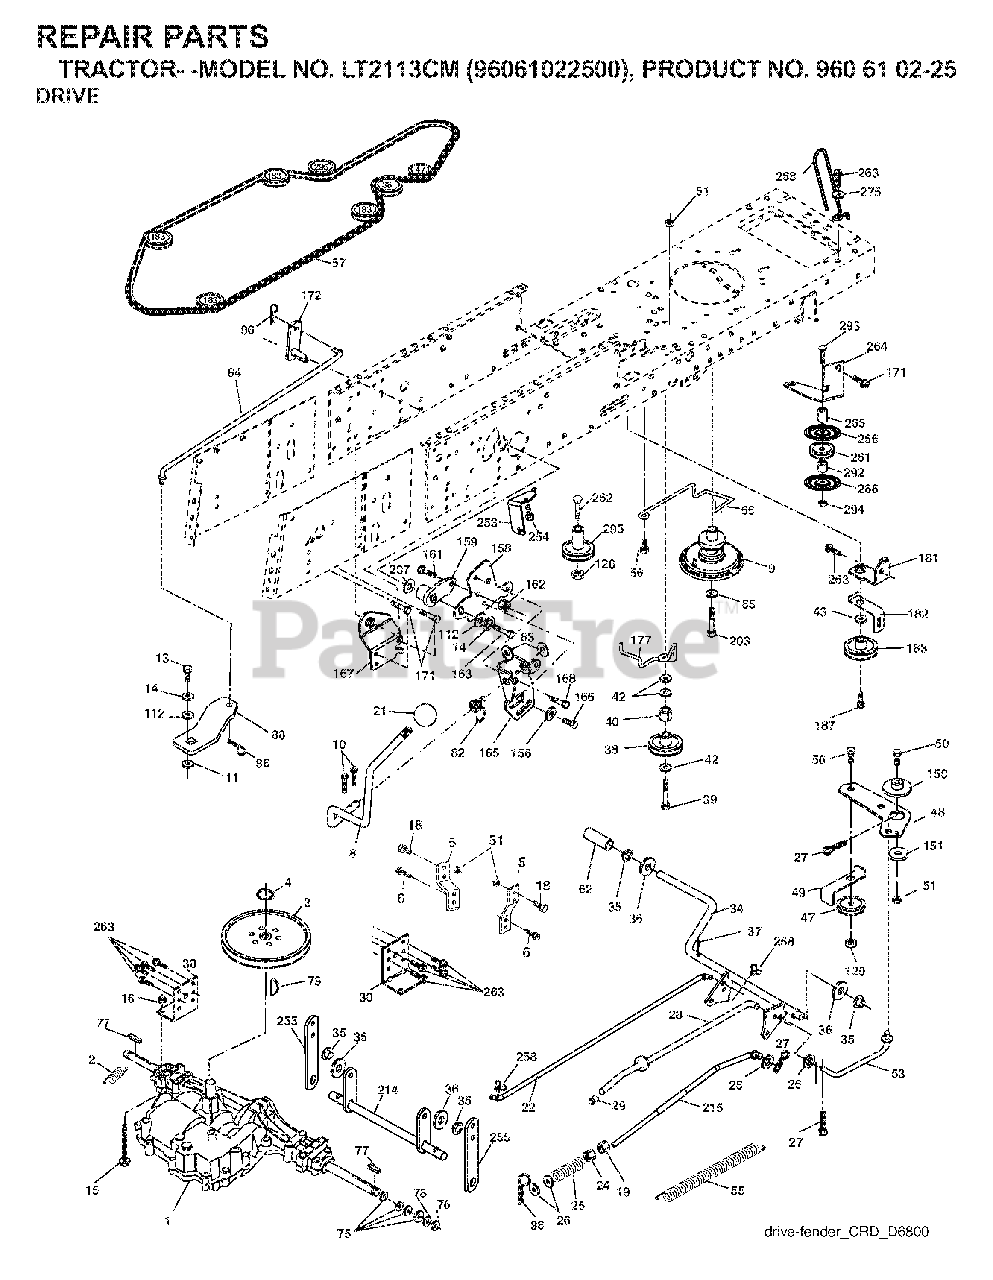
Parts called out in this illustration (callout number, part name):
2	SPRING,BRAKE RETURN
4	RETAINING RING LT
5	STRAP TORQUE
6	SCREW 5/16"
8	ROD SHIFT FENDER ADJUST LT
10	PIN COTTER
11	WASH-SHFT PLT LT
13	BOLT 1/4-28X3/4
14	LOCKWASHER
15	BOLT HEX 5/16-18 GR 5
16	NUT.71038.31-18.HEX.NYLOCK
18	BOLT
19	NUT
21	KNOB T (1/2-HOLE)
24	NUT
25	SPRING ROD LT
27	COTTER PIN
28	ROD, PARKING BRAKE
29	PLUNGER CAP
30	BRKT, MOUNT TRNSAXLE
34	SHAFT, FOOT PEDAL
35	BEARING.NYLON
36	WASHER LT
37	DRIVE PIN
38	PULLEY.FLAT
42	WASHER
43	WASHER T
47	IDLER PULLEY
48	BELLCRANK, CLUTCH
49	RETAIN BELT
50	BOLT.3/8-16X1.50
51	LOCKNUT
53	LINK.CLUTCH.7.66.2005
55	SPRING, RETURN LT
56	SCREW.3/8-16
62	PEDAL COVER T
65	LOCKWASHER
66	KEEPER BELT ENGINE
76	E-RING LT
77	SQUARE KEY
80	ARM SHIFT
82	SHIFT SPRING
83	WASHER
96	RETAINER M
112	WASHER LT
120	NUT LOCK FLG 3/8-16 UNC
150	BUSHING.BELLCRANK.GRD.DR
151	WASHER 12/32X2X10GA
156	WASHER.SRRTD.5/16
158	BRACKET
159	HUB.SHIFT
161	BOLT
162	NUT.CROWNLOCK.1/4
163	BOLT
165	RP BRACKET
166	SCREW
167	BRACKET
168	BOLT.SHOULDER.5/16-18X
171	SCREW LT
187	BOLT.5/16-18X1.25
207	WASHER NYL
254	SCREW 3/8-16X1
258	CLIP RETAINER
261	FLAT IDLER PULLEY
263	SCREW, 3/8-16X3/4
275	WASHER
294	NUT, HEX 3/8-16
295	PULLEY IDLER COMPOSITE
